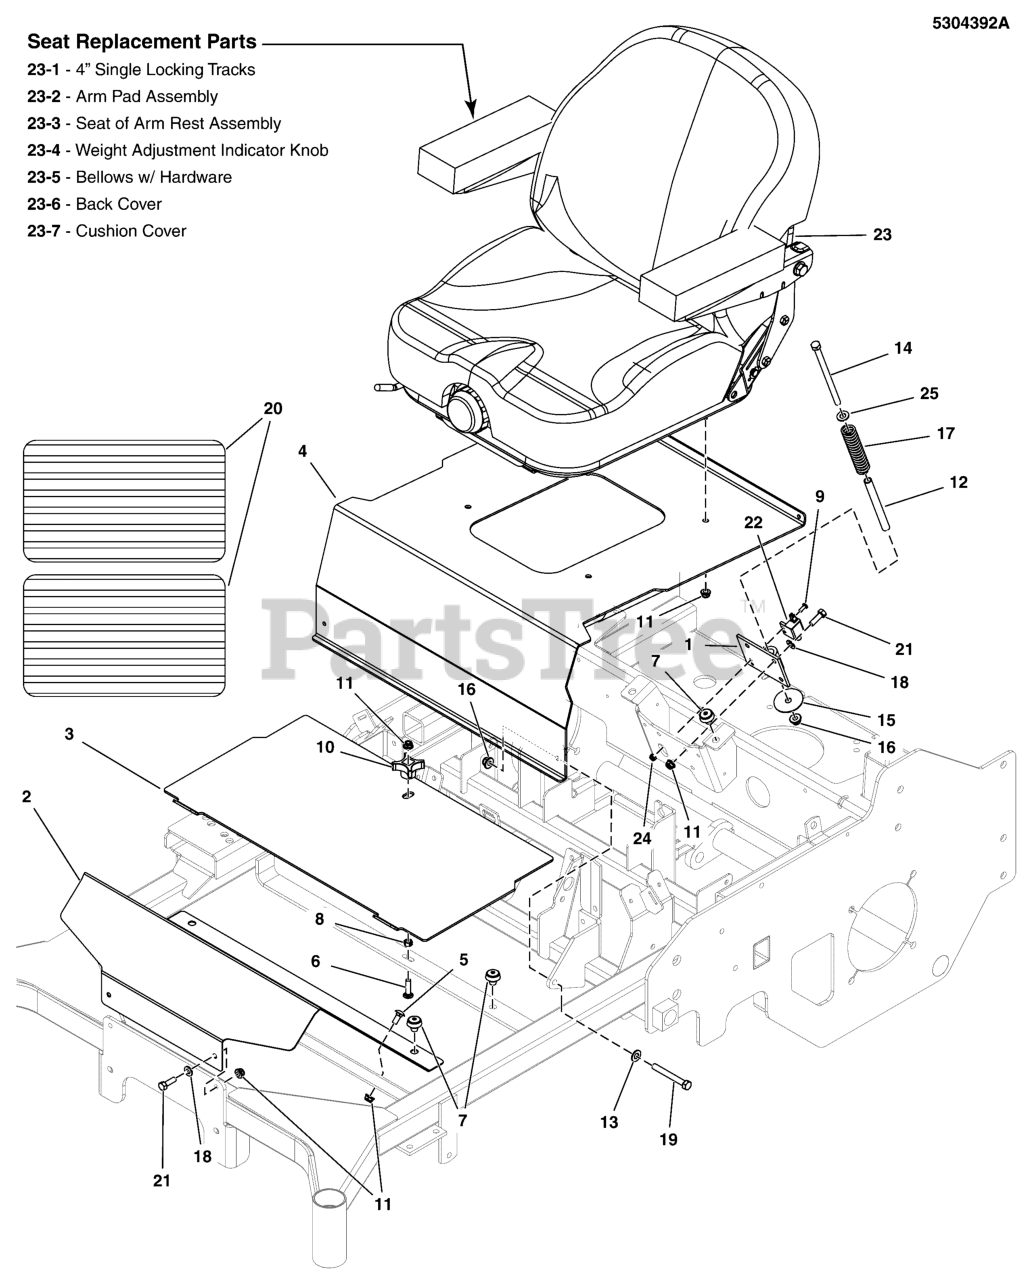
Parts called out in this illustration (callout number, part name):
1	WELD, SEAT SWITCH
2	PLATE, RIGID FLOOR, 200XT - RED
3	PLATE, REMOVABLE FLOOR, 200XT - RED
4	ASSM, SEAT PLATE W/ DECAL, F320Z-DOM
5	BOLT, 5/16-18 X 3/4, CARRIAGE, GD5, CZ
6	BOLT,5/16-18X1.500,CARRIAGE,SQ,GR5,ZC/CL
7	MNT, VBRTN, RBBR
8	NUT, 5/16-1/8, HEX, CNTR LK, ZINC PHOS/OIL
9	SCREW, #10-24 X 3/4" ROUND PHILLIPS
10	KNOB-INT THR .312-18 4-ARM 2.12WD 1.06LG
11	NUT, 5/16-18 HEX NYLOCK FLANGE NUT
12	SPACER, .38 X .50 X 5.06, CZ
13	WASHER, 3/8 SAE
14	BOLT, 3/8-16 X 6" GD5 CZ
15	WASHER, .39 X 2.00 X X .14
16	NUT, 3/8 - 16 HEX NYLOCK FLANGE
17	SPRING, .688 ID X .130 WIRE DIA 4.25
18	WASHER, 5/16" SAE
19	BOLT, 3/8-16 X 3" GD5 CZ
20	SAFETY WALK, 10.00 X 19.00
21	BOLT, 5/16-18 X 1" GRD5 YZ
22	SWITCH, PLUNGER, N.C.
23	SEAT, MID BACK, W/SUSPENSION, SEATS INC
23-1	4" SINGLE LOCKING TRACKS BASE
23-2	ARM PAD ASSEMBLY BLK/CHAR CAR FIB/HARBR GRY RED WELT
23-3	SET OF ARMREST ASSEMBLY BLK/CHAR CAR FIB/HARBR GRY RED WELT
23-4	WEIGHT ADJUST INDICATOR KNOB ASSY BASE
23-5	BELLOWS W/ HARDWARE BASE
23-6	BACK COVER FOR FIXED BACK I3M BLK/CHAR CAR FIB/HARBR GRY RED WELT
23-7	CUSHION COVER FOR I3M BLK/CHAR CAR FIB/HARBR GRY RED WELT
24	NUT, Hex, Nylon Lock, #10-24
25	WASHER, 3/8" USS
